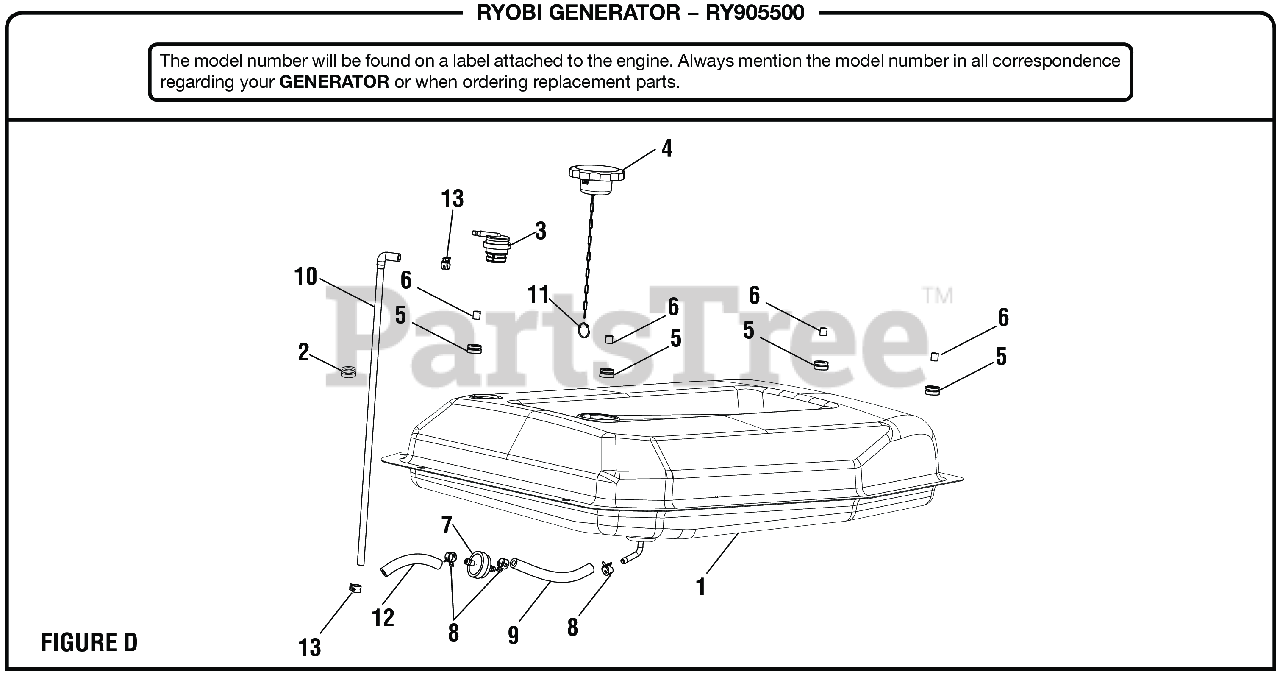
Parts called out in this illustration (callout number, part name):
1	Fuel Tank
2	Fuel Hose Protector
3	Fuel Tank Vapor Vent
4	Fuel Cap Assembly
5	Bushing (Fuel Tank Isolator)
6	Spacer (Fuel Tank Isolator)
7	Fuel Filter Inline (1/4 in.)
8	Fuel Line Clamp (1/2 in.).
9	Fuel Hose (175 mm)
10	Vapor Hose
11	Ring Clip
12	Fuel Hose (85 mm)
13	Fuel Line Clamp (7/16 in., BM903611)
